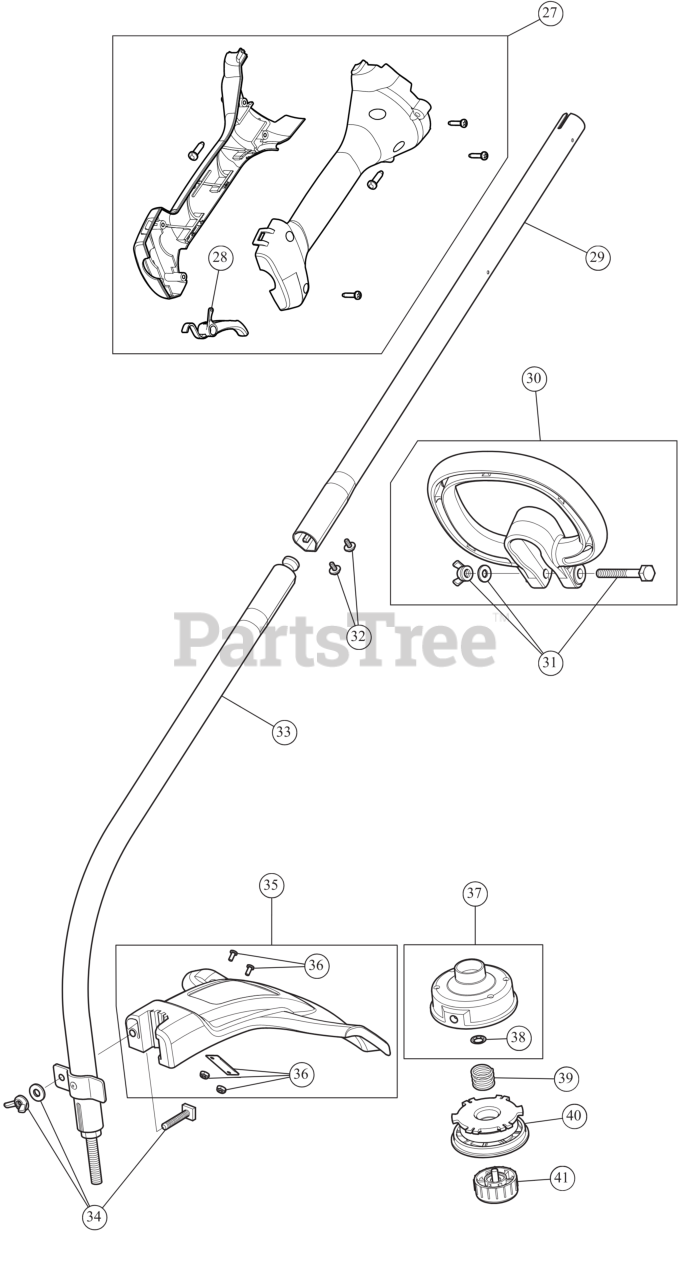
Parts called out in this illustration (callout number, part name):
27	THROTTLE GRIP ASSEMBLY
28	THROTTLE TRIGGER
29	UPPER BOOM ASSEMBLY
30	HANDLE
31	HANDLE HWD
32	SCREW 8-32X3/8
33	LOWER BOOM ASSEMBLY
34	BLADE GUARD MOUNTING HARDWARE
35	GUARD ASSEMBLY
36	BLADE ASSEMBLY CUTOFF
37	REEL:OTR W/RET
38	RETAINER .625 OD 2
39	SPRING-SPOOL
40	REEL-INNER SPOOL
41	BUMP HEAD KNOB ASSEMBLY
